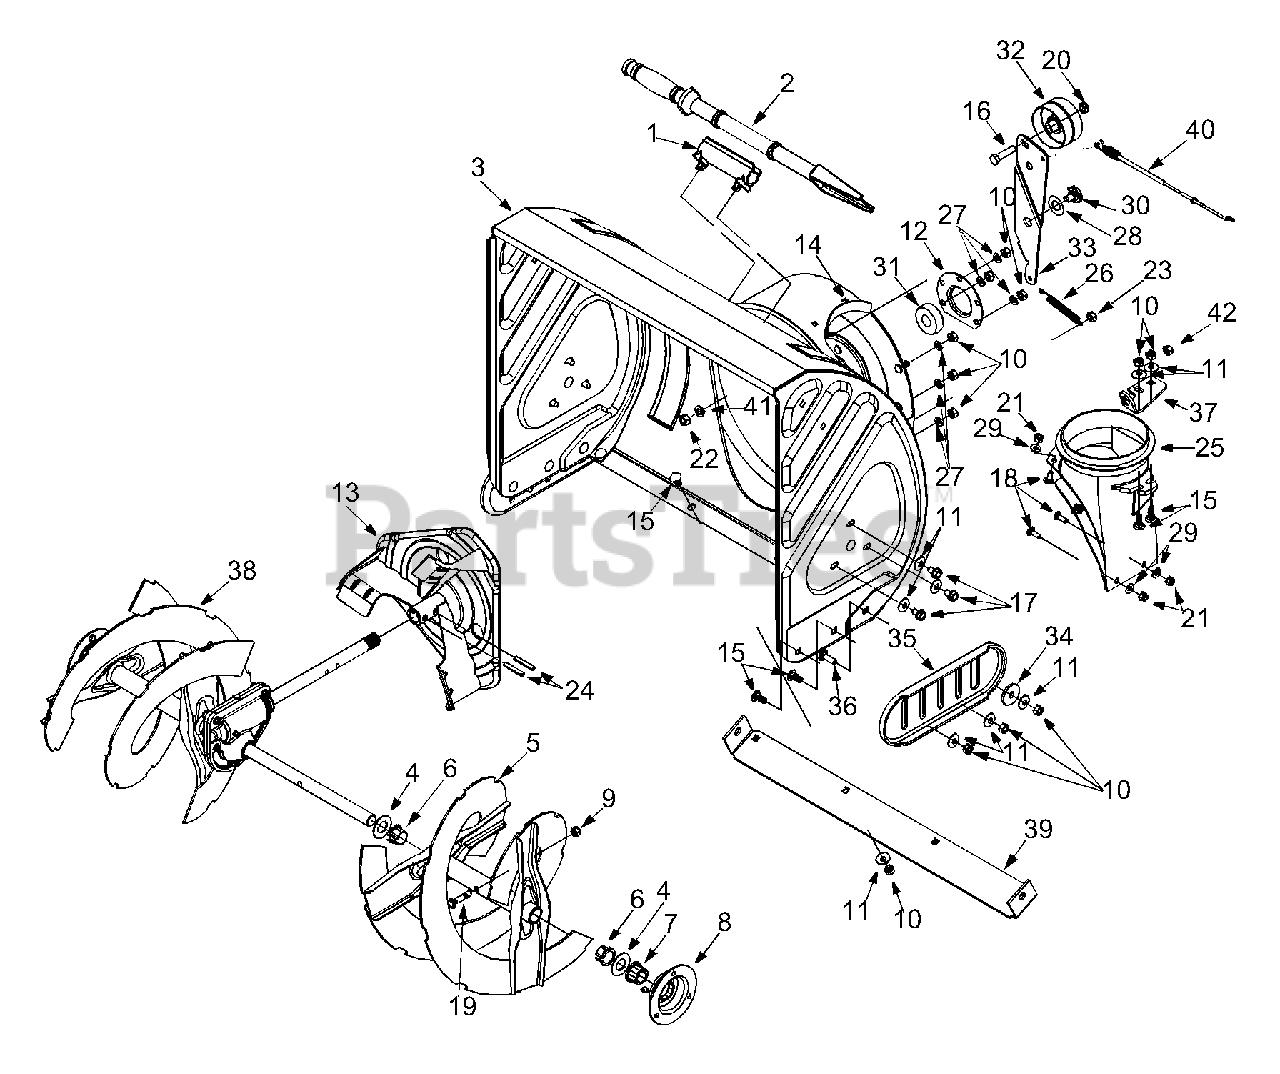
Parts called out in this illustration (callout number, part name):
1	Mount, Chute Clean-out Tool
2	Chute Clean-out Tool
6	Flange Bushing
7	Hex Flange Bearing
8	Bearing Housing
9	Lock Nut 5/16-18 Thd.
10	Hex Nut 5/16-18 Thd.
11	Bell Washer
15	Carriage Bolt 5/16-18 x .75
16	Hex Cap Screw 3/8-24 x 1.50
17	AB Screw 5/16-12 x 0.75
18	Carriage Screw 1/4-20 x .75
19	Shear Bolt 5/16-18 x 1.5
20	Lock Jam 3/8-24
21	Hex Flange Nut 1/4-20
22	Hex Nut 3/8-16
23	Hex Nut 5/16-18
25	Chute Adapter
26	Extension Spring
27	Lock Washer 5/16
28	Flat Washer .565 x 1.25 x .02
30	Shoulder Screw
31	Ball Bearing
32	Flat Idler
34	Flat Washer .38 x 1.38
36	Carriage Screw 5/16-18
40	Auger Clutch Cable
41	Lock Washer 3/8
42	Plastic Bushing
